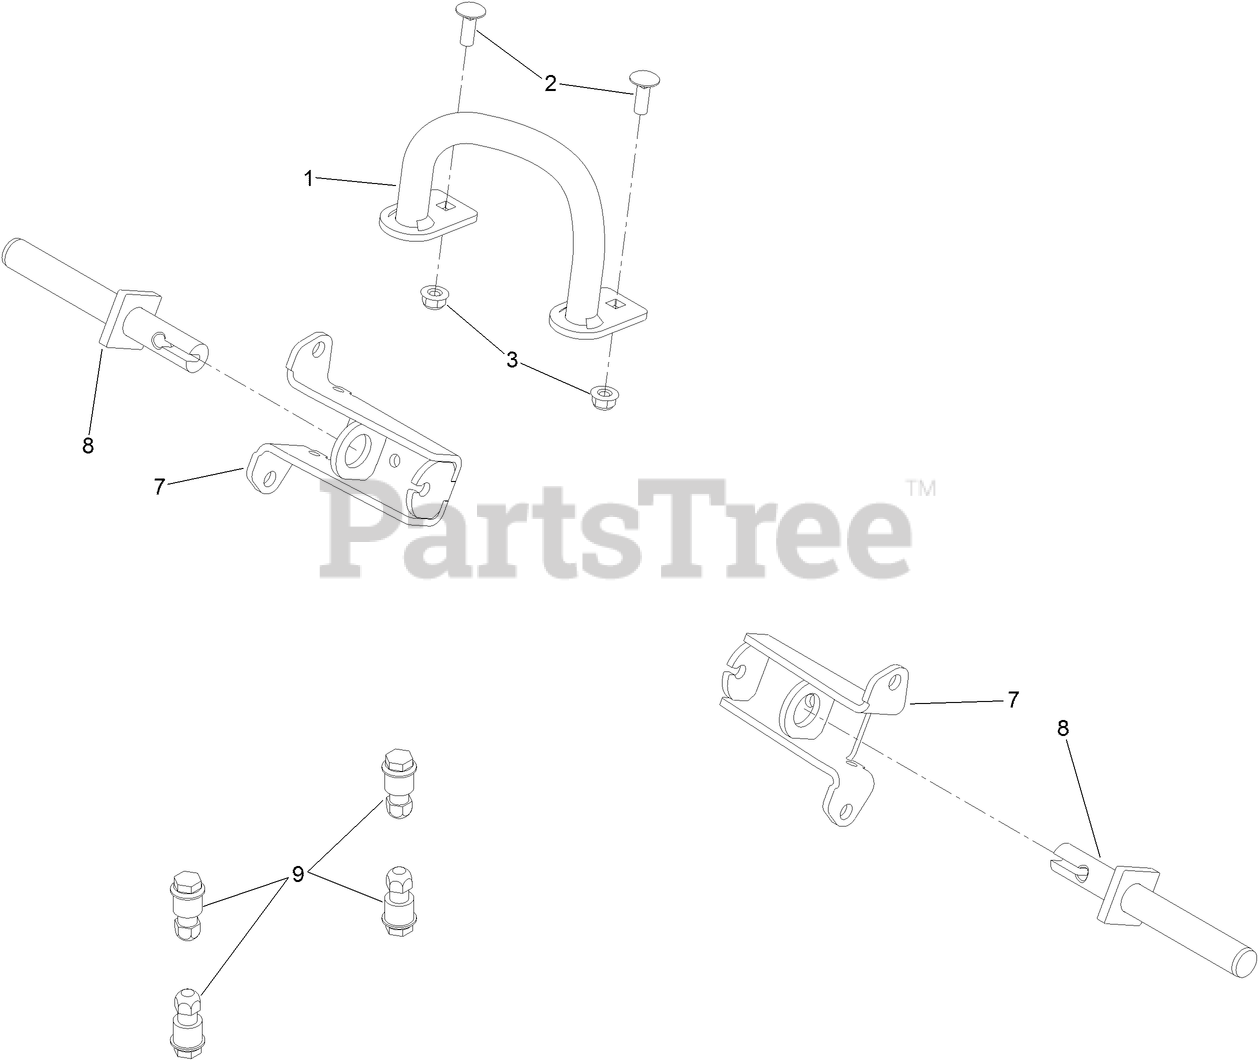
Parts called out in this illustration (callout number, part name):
1	BAR-REFERENCE
2	BOLT-CARR
3	NUT-HF, NI
7	MOUNT-BRAKE
8	ROD-BRAKE
9	VALVE-RELIEF
